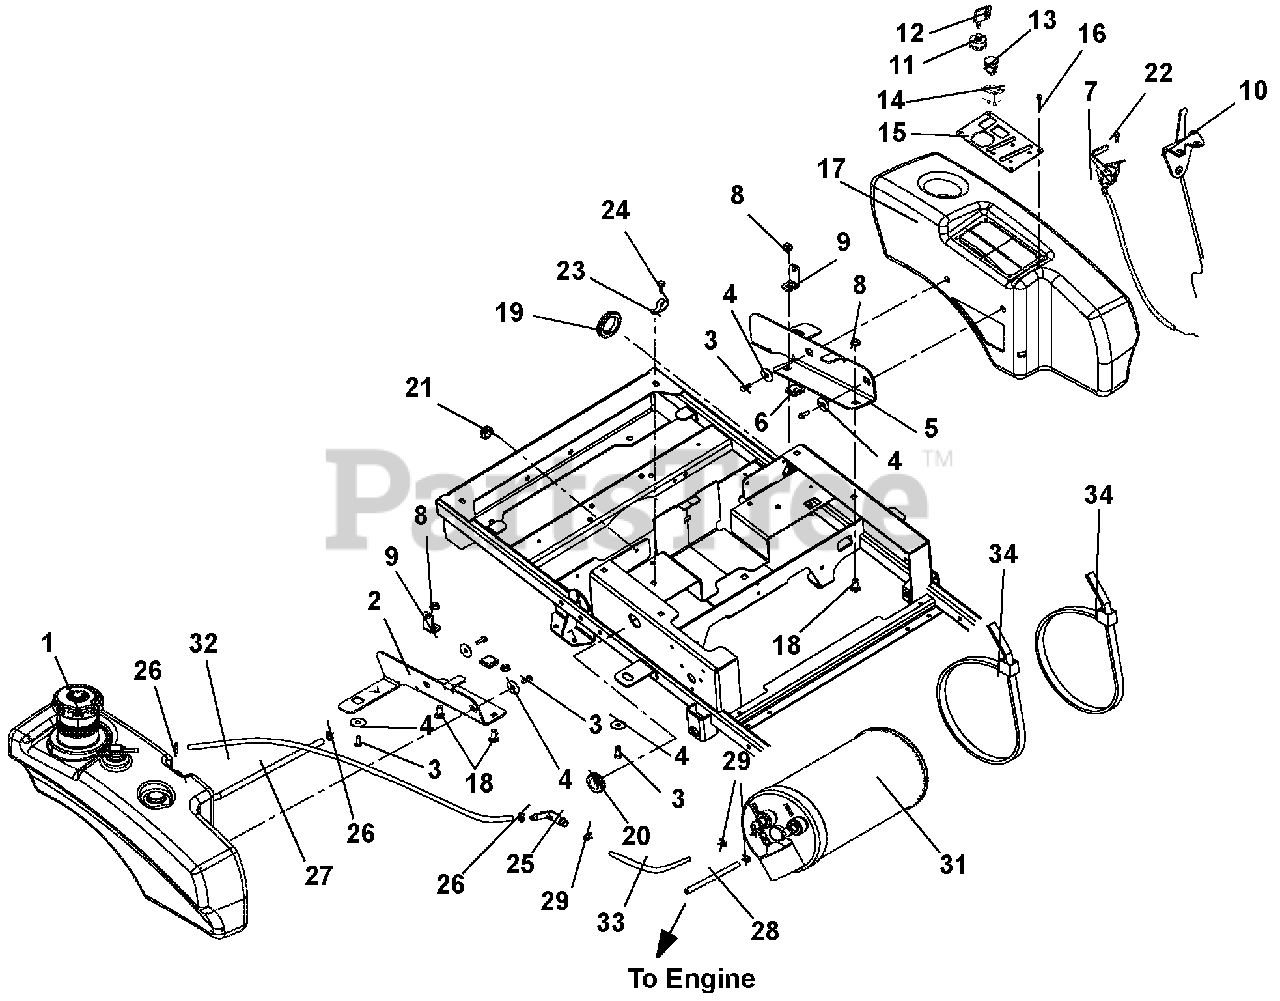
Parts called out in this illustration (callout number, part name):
1	TANK, XL NON-PERM ASSEMBLY
2	BRKT, RH REAR TANK MOUNT
3	BLT-SERHFWH .312-18X.50 YWZC
4	WSHR-FL-STL .347X1.254X.048YWZ
5	BRKT, LH REAR TANK MOUNT
6	GRIP, RUBBER (1.0X1.0X.187)BLK
7	CABLE, XL THROTTLE
8	@NUT-LK-NYL-FLG .38-16 YWZC
9	BRKT, HOOD PIVOT
10	CABLE, XL CHOKE
11	KEY SWITCH
12	KEY -W/CAP
13	SWITCH, CLUTCH
14	METER, HOUR W/MAINTENANCE
15	CONTROL PANEL
16	SCR-HEX .25X14-.75
17	FENDER, XL
18	@BLT-RDHDSQNK .38-16X1.00 G5YZ
19	GROMMET 1.70ID X 2.0OD
20	GROMMET 1.0ID X 1.38 OD
21	GROMMET,RUBBER 5/8 ID/1.13 OD
22	@SCR-TAP 10-24X.50 HWH TR YWZC
23	CLAMP, CUSHIONED STEEL .75
24	@SCR-TAP .38-16X.50 HWH TR YWZ
25	FITTING-3/16X1/4 90DEGREE VAC
26	CLAMP, FUEL LINE
27	HOSE, .25 LOW-PERM BULK GAS
28	HOSE, .188 LOW-PERM BULK GAS
29	CLAMP-HOSE, SPRING .188
30	CAP, END .315 X 1.00
31	400 CC CARBON CANISTER 3/16 PT
32	HOSE, .25 LOW-PERM BULK GAS
33	HOSE, .188 LOW-PERM BULK GAS
34	TIE WRAP
